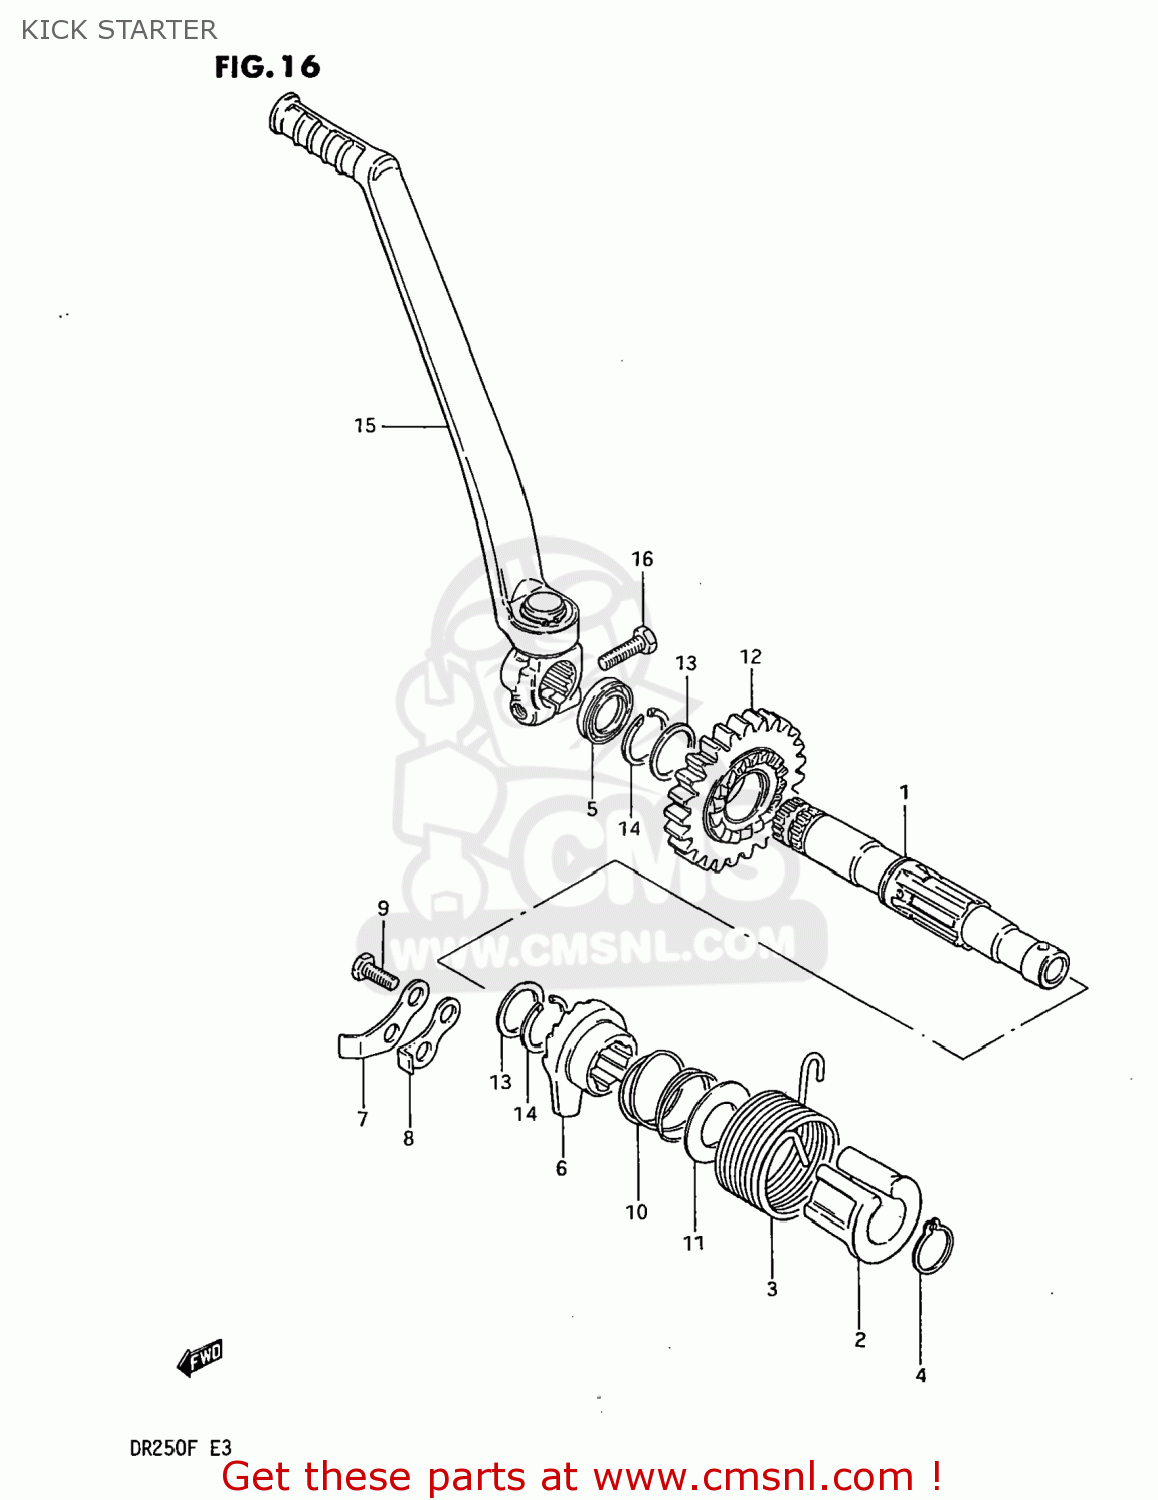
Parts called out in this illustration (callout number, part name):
1	SHAFT,KICK STARTER
2	GUIDE,KICK STARTER SFT SPRING
3	SPRING
4	CIRCLIP
5	SEAL,OIL(20X27X5)
6	STARTER,KICK
7	GUIDE,KICK STARTER
8	STOPPER,KICK STARTER
9	BOLT
10	SPRING
11	WASHER
12	GEAR,KICK STARTER DRIIVE
13	SHIM
14	CIRCLIP
15	LEVER ASSEMBLY,KICK STARTER
16	BOLT 8X25
